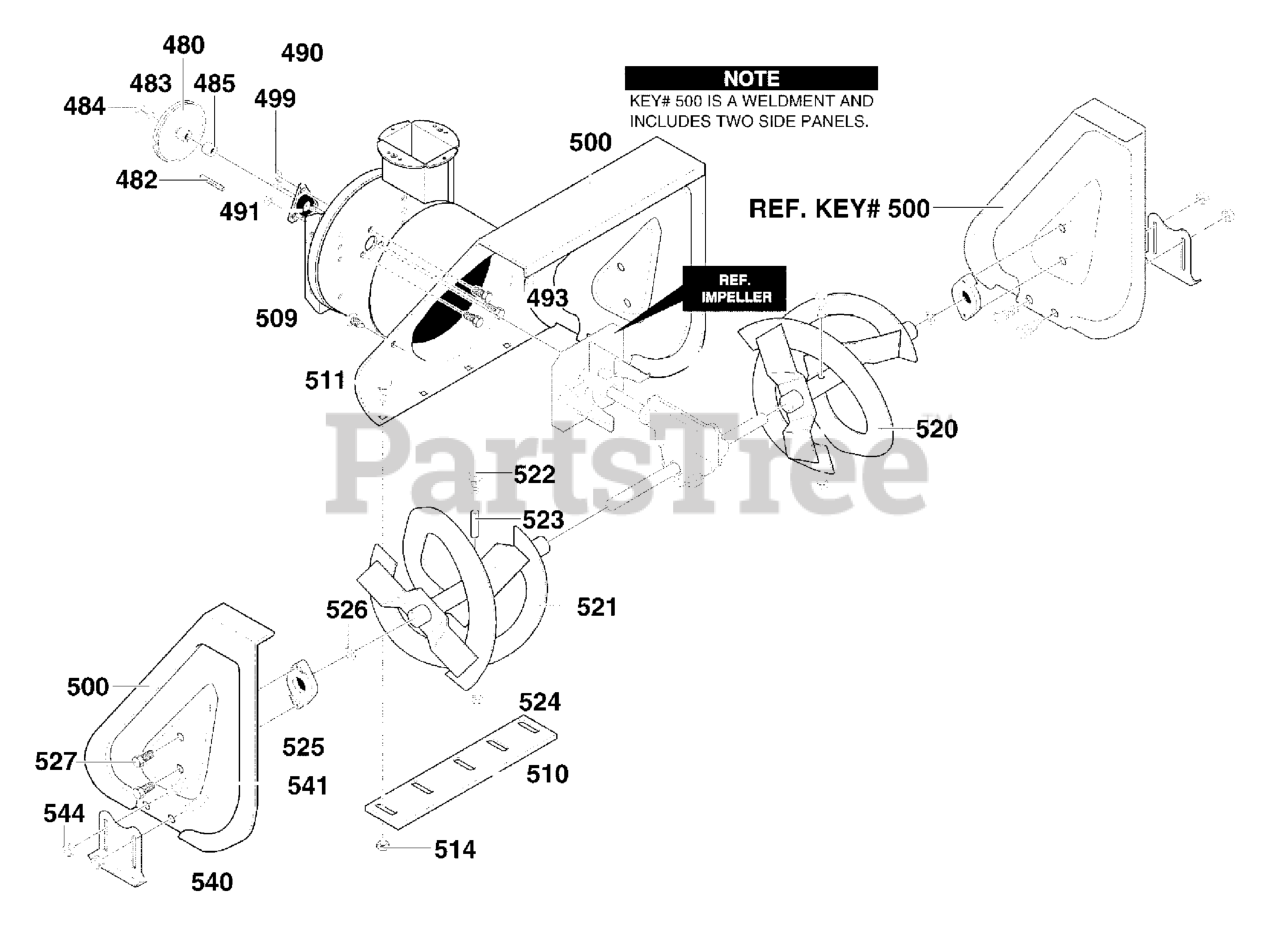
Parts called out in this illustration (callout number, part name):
480	PULLEY, V4L
482	KEY, SQUARE
483	WASHER, FLAT
484	NUT, 1/2-20
485	SPACER, SLEEVE
490	RETAINER, BALL
491	BEARING, BALL
493	SCREW, 5/16-18 x 0.75
499	NUT, 5/16-18
500	HOUSING, ASSY
509	PLUG, CHRISTMAS TREE
510	SCRAPER BLADE
511	BOLT, CARRIAGE
514	NUT, HEX
520	AUGER, LH
521	AUGER, RH
522	SCREW, 1/4-20X1.75
523	SPACER, SLEEVE
524	NUT, 1/4-20
525	BEARING, AUGER SHAFT
527	SCREW, 5/16-18 x 0.75
540	SKID, HEIGHT ADJUST
541	BOLT, 5/16-18X .75
542	FLATWASHER
543	WASHER
544	NUT, 5/16-18
